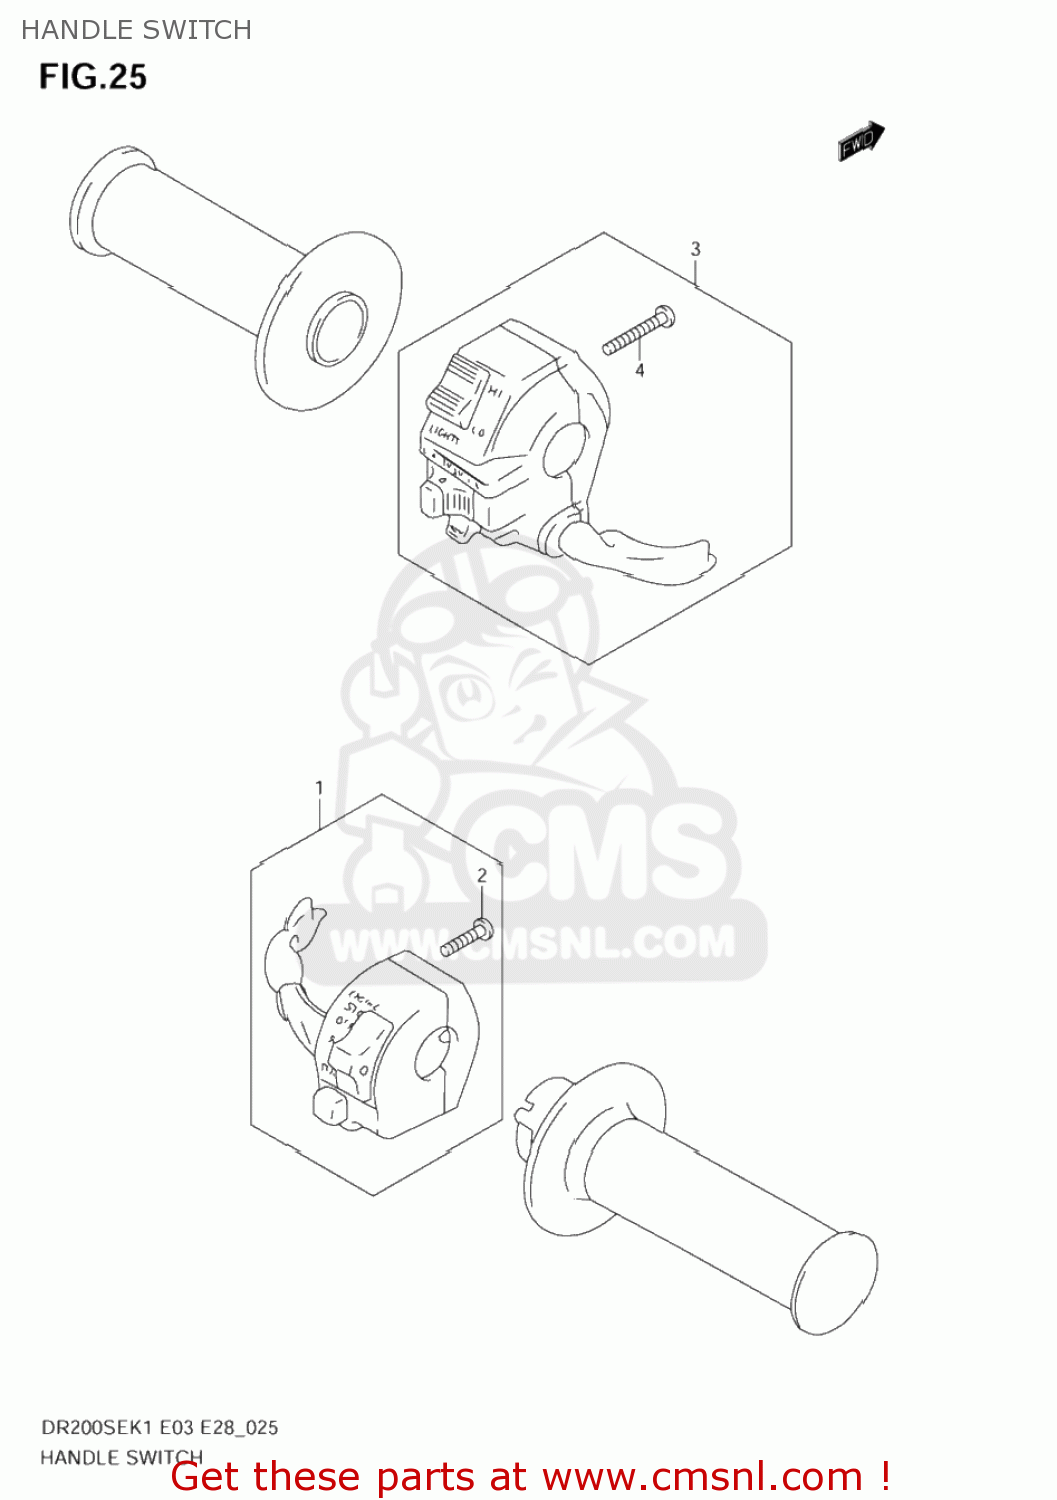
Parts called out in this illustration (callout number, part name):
1	SWITCH ASSY,HANDLE,R
2	SCREW
3	SWITCH ASSEMBLY,HANDLE,LEFT
4	SCREW
